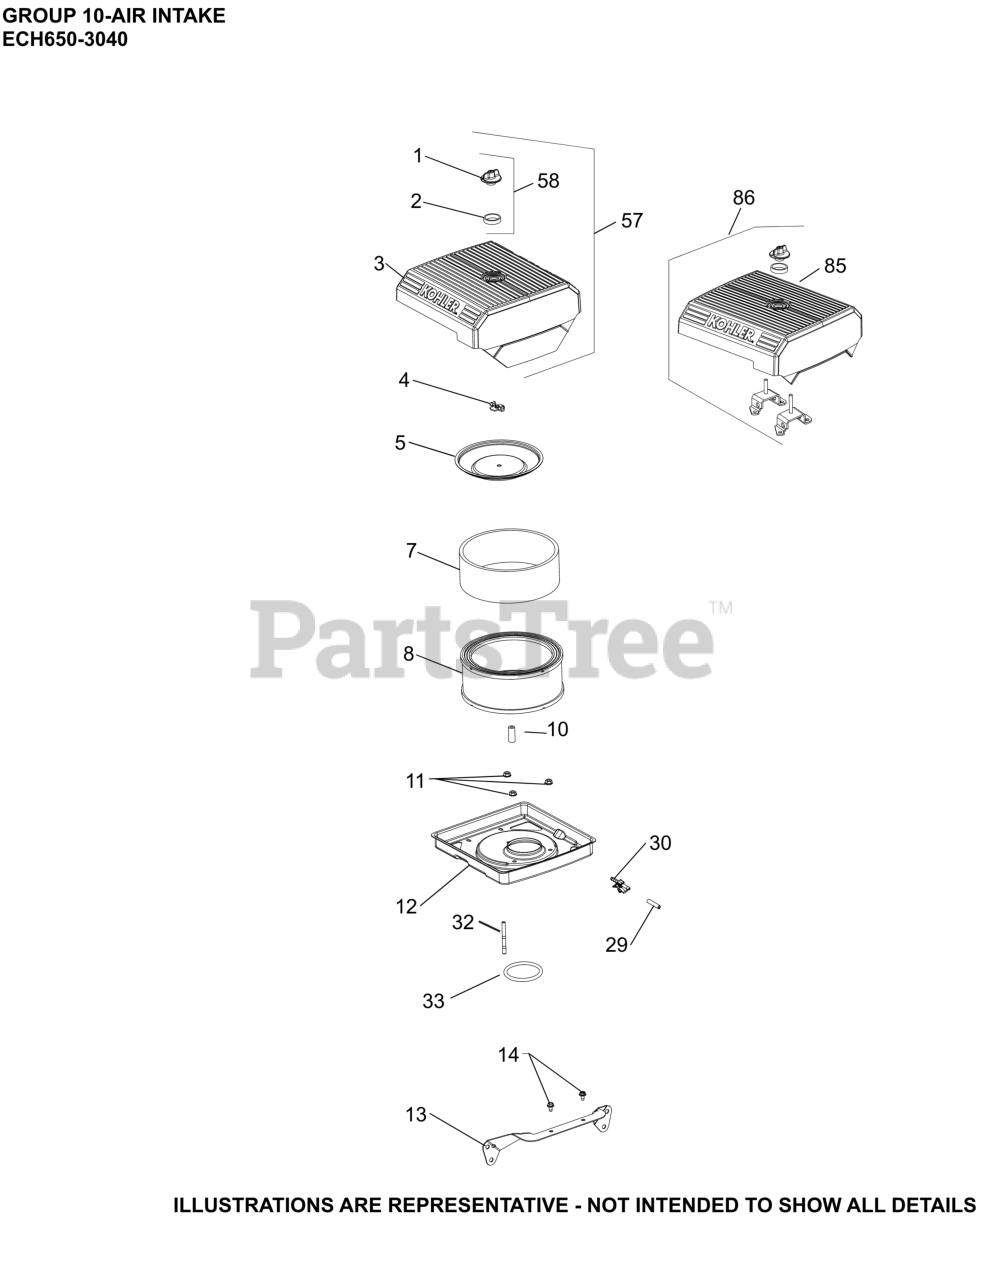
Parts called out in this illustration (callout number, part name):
1	KNOB, COVER
3	COVER, AIR CLEANER
4	NUT, WING
5	COVER, INNER AIR CLEANER
7	PRE CLEANER LOW ELEMENT
8	ELEMENT, AIR CLEANER
11	NUT, FLG M6X1.0
12	BASE, AIR CLEANER
13	AIR CLEANER BRACKET
14	SCREW, THREAD FORMING
29	CAP, MASKING
30	CONNECTOR, EVAPORATIVE
32	STUD, LOW PROFILE A/C
33	O-RING, AIR CLEANER BASE
57	KIT, AIR CLEANER COVER
58	KIT, KNOB W/SEAL
NI	COVER, AIR CLEANER
NI	KIT, AIR CLEANER COVER
